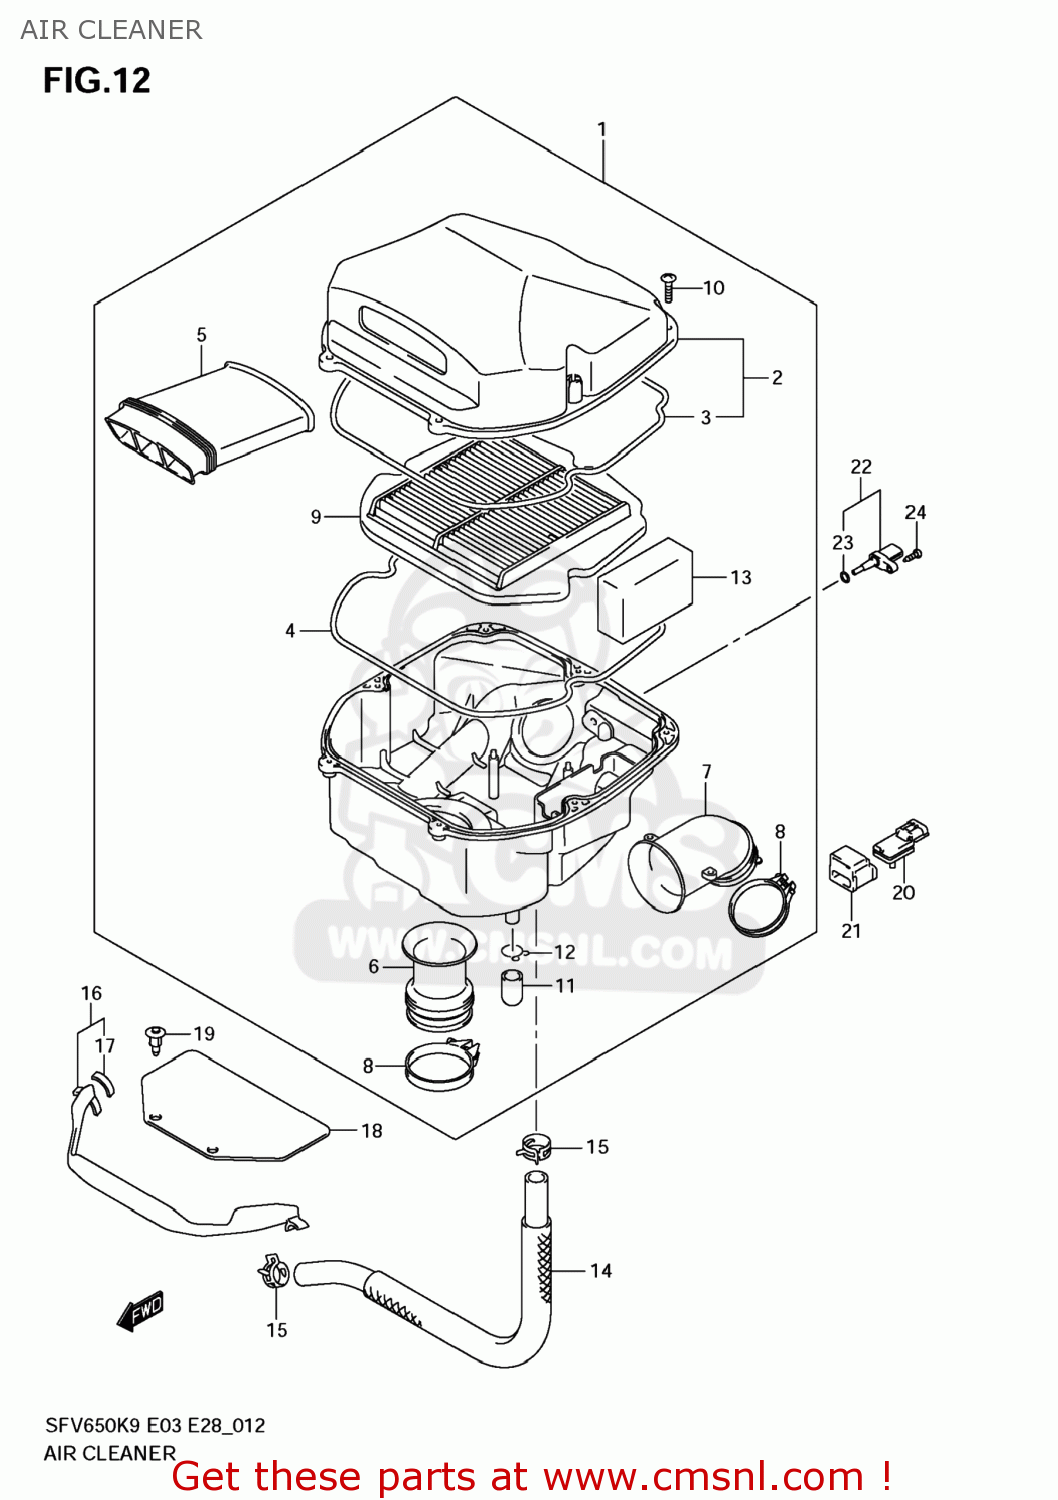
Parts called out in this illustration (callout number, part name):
1	CLEANER ASSY,AIR
2	CAP,AIR CLEANER
3	GASKET (NAS)
4	GASKET (NAS)
5	TUBE,INLET
6	TUBE,OUTLET
7	TUBE,OUTLET
8	CLAMP,OUTLET T
9	FILTER,AIR CLEANER
10	SCREW
11	PLUG
12	CLIP
13	FILTER,BREATHER
14	TUBE,BREATHER
15	CLIP
16	COVER,CLEANER INLET
17	CUSHION
18	SHEET,CLEANER INLET
19	CLIP(BLACK)
20	SENSOR,PRESSURE
21	HOLDER,SENSOR
22	SENSOR,AIR TEMP
23	O RING
24	SCREW
